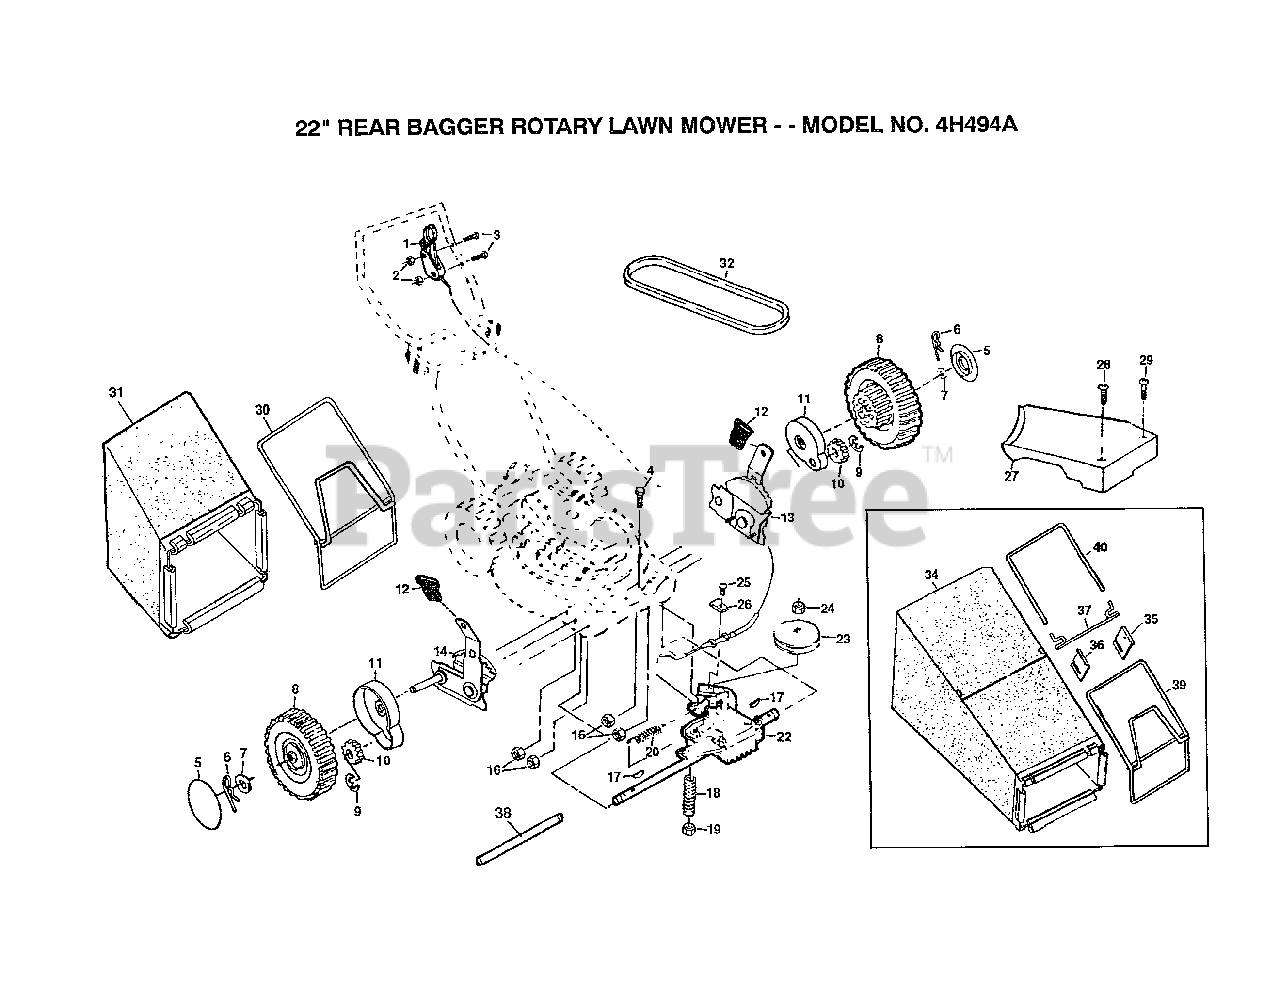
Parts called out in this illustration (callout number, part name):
1	CONTROL.DRIVE
3	SCREW
4	BOLT PM
5	HUB CAP
6	RETAINER CLIP PM
7	WASHER
8	WHL & TIRE ASS'Y
9	RING T
10	PINION.10.TEETH
12	KNOB PM
17	WOODRUFF KEY
20	SPRING
23	DRIVE PULLEY
24	LOCKNUT
25	SCREW WASHER HD
26	CABLE CLAMP
27	DRIVE COVER
30	CATCHER FRAME
31	GRASS BAG
32	V-BELT.LM.DRIVE
35	BRKT.HANG.HDLE LH
36	BRKT.HANG HNDL.RH
37	BRKT.HNG GRASSBAG
38	DRV SHAFT TUBE PM
39	FRAME THROAT ASSY
